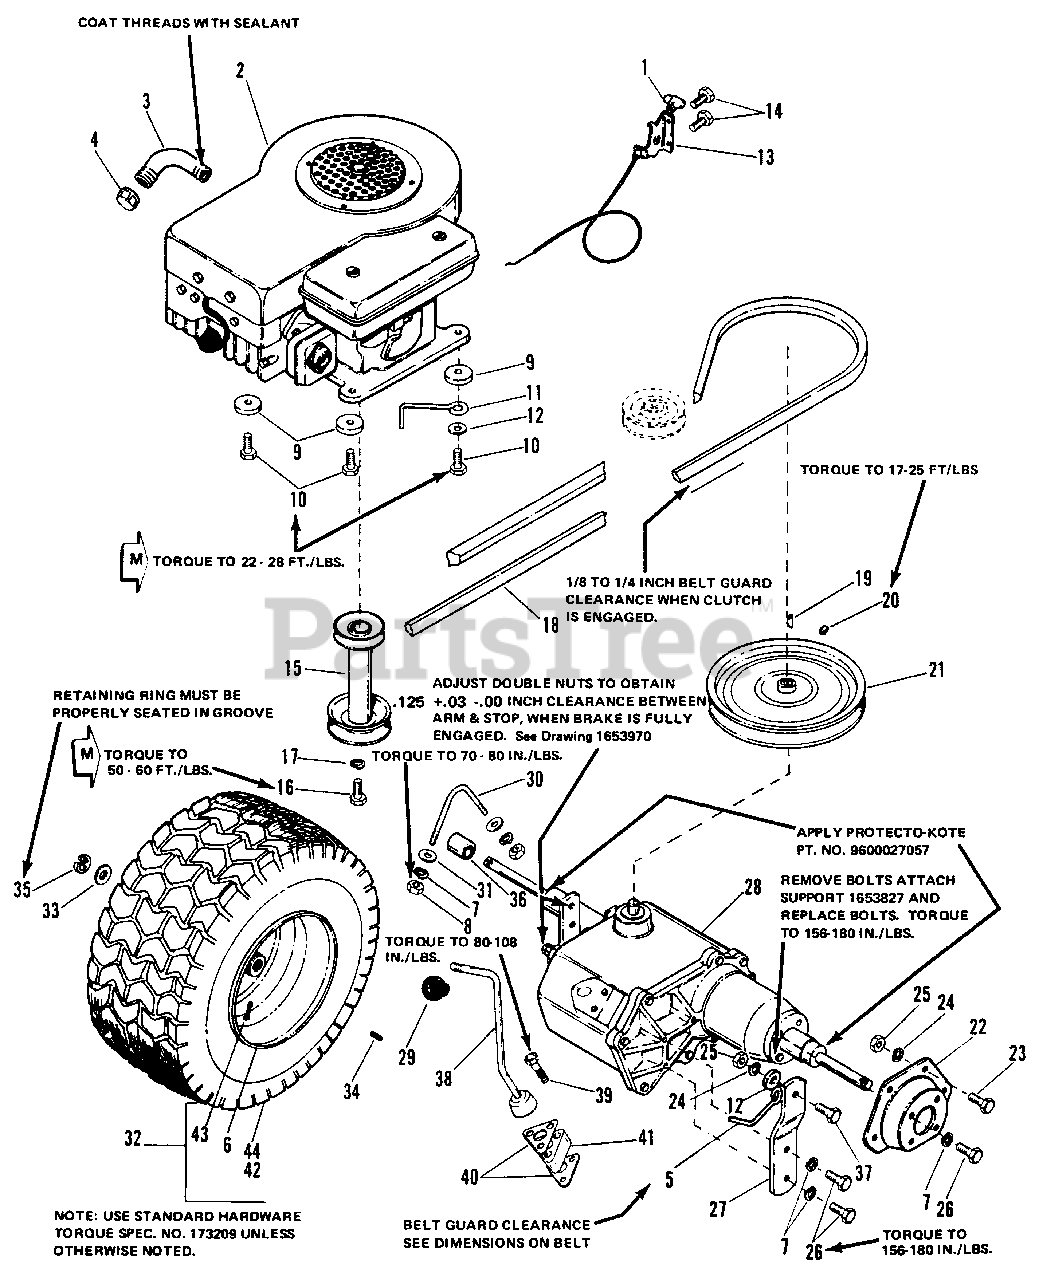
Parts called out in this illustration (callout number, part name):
1	KNOB
2	ENGINE, (Electric Start) B/S Model
4	CAP, Pipe, 3/4
7	LOCKWASHER, 5/16
8	NUT, Hex, full 5/16-18
9	WASHER, Special
10	SCREW, Taptite, 3/8-16 x 1-3/4
12	WASHER, Plain
13	CONTROL, Throttle
14	SCREW, Taptite, 1/4-20 x 3/4
15	PULLEY, Engine
16	CAPSCREW, 7/16-20 x 1-1/4
17	LOCKWASHER, 7/16
18	V-BELT, Arbor Drive, 50"
19	KEY
20	SETSCREW, 5/16-18 x 1/2
21	PULLEY, 10"
22	SUPPORT, Axle, L.H.
23	CAPSCREW, 3/8-16 x 3/4
24	LOCKWASHER, 3/8
25	NUT, Hex 3/8-16
26	CAPSCREW, 5/16-18 x 1
27	SUPPORT, Strap
28	TRANSAXLE
30	BOLT, Axle
31	WASHER, Plain, 5/16
32	WHEEL & TIRE (4108)
34	KEY
35	RING, Retaining
37	CAPSCREW, 3/8-16 x 1-1/4
38	LEVER, Shift
39	SCREW, Washer head, 1/4-20 x 1-3/4
40	GASKET
41	BLOCK, Riser
42	CARLISLE TIRE
43	VALVE STEM & CAP
44	GOODYEAR TIRE
